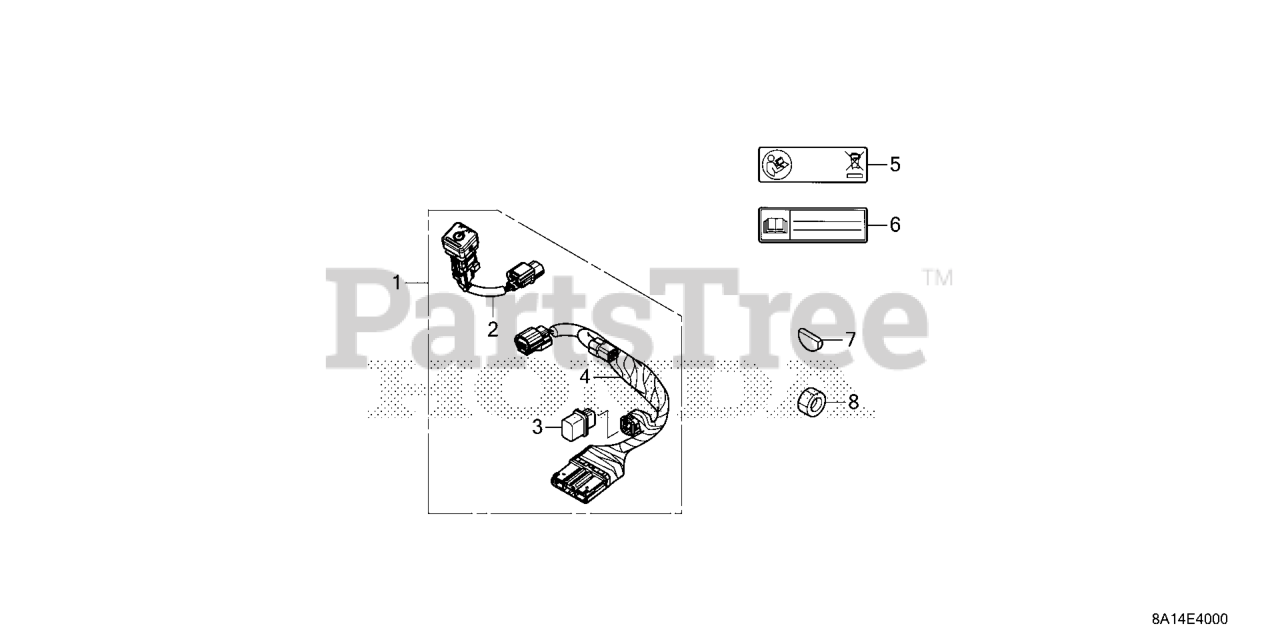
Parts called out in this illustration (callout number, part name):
1	CORD KIT, PC
2	SWITCH ASSY., POWER
3	TERMINATOR ASSY.
4	WIRE, PC
